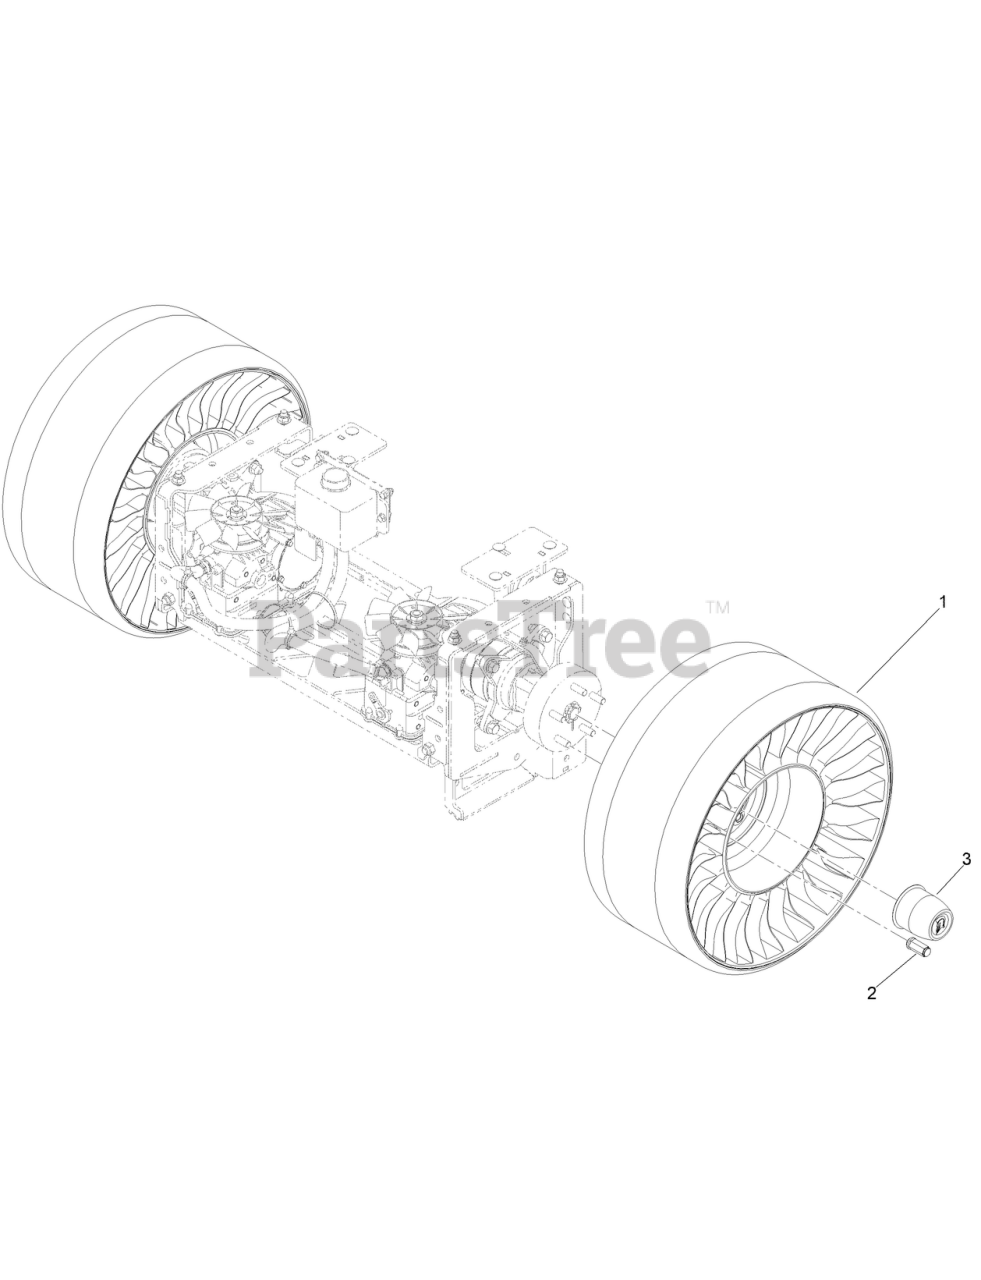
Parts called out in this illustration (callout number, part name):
1	TWEEL 24X12N12L 54411
2	LUG NUTS
3	RR STEEL WHEEL SILVER CNTR CAP
